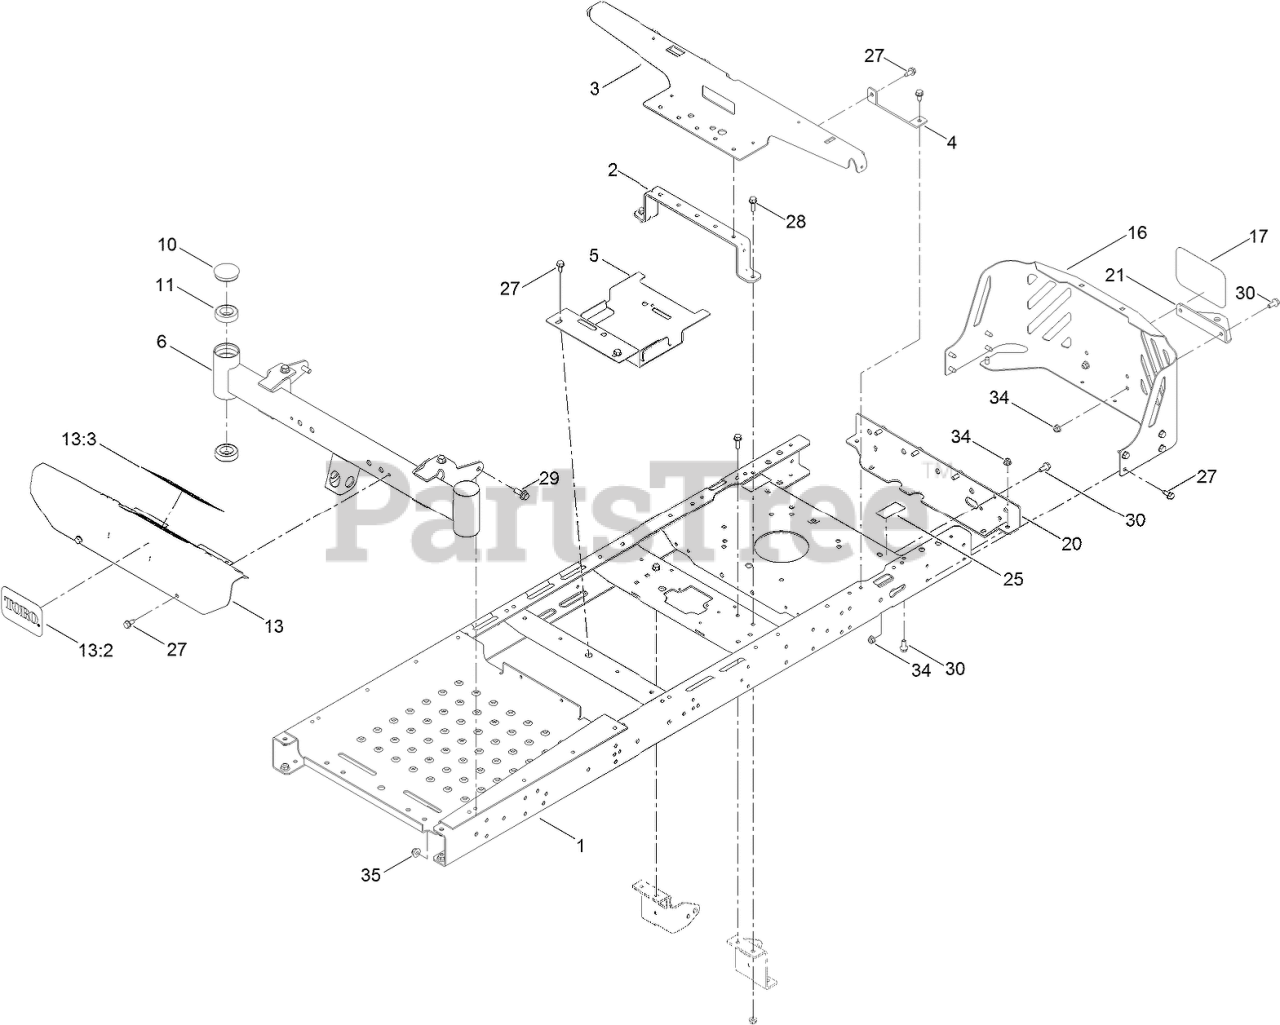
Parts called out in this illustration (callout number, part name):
1	FRAME ASM
2	BRACE-SEAT, REAR (NARROW)
3	SUPPORT-POD
4	SUPPORT-TANK, REAR
5	BRACKET-BATTERY
6	AXLE-FRONT, NARROW
10	CAP-GREASE
11	BEARING-BALL
13	FOOTREST ASM
13:3	DECAL-DANGER
16	GUARD-ENGINE, NARROW
17	DECAL
20	CROSSMEMBER-REAR, NARROW
21	BRACKET-HITCH
25	DECAL-BYPASS
27	SCREW-HWHTF
28	SCREW-HHF
29	SCREW-HHF
30	SCREW-HHF
34	NUT-HF, NI
35	NUT-HF, NI
